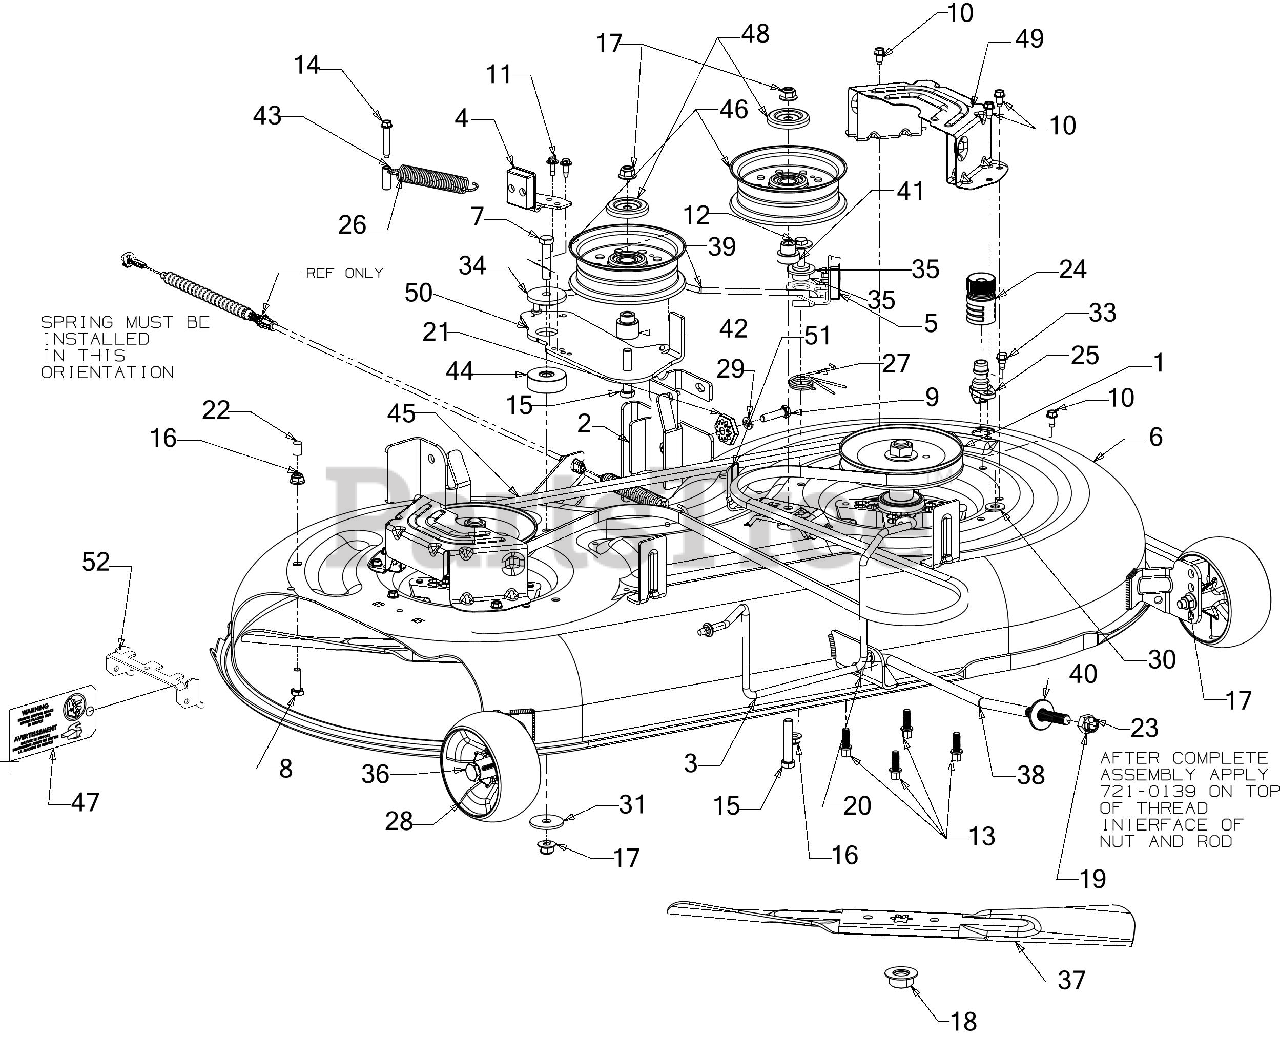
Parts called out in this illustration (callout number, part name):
1	SPINDLE ASSEMBLY
2	DECK HANGER BRACKET ASSEMBLY (LH)
3	BELT KEEPER ROD
4	DECK BRAKE ASSEMBLY
5	DECK BRAKE ASSEMBLY
6	42" DECK ASSEMBLY
7	HEX SCREW 3/8-16 x 1.75 GR5
8	SCREW 5/16-18 x 1.0 GR5
9	SCREW 5/16-18 x 1.25 GR5
10	SCREW 1/4-20 X.500
11	SCREW M6-1 x .625
12	SCREW 5/16-18 x 1.25 GR5
12	SCREW 5/16-18X1.25 GR 5
12	FLAT WASHER 344X1.00
13	SCREW 5/16-18 X .875
14	SCREW 1/4-20 x 1.50"
15	SCREW 3/8-16 x 2.0 GR 8
16	FLANGE LOCK NUT 5/16-18
18	HEX NUT
20	PIN:COTTER
21	DECK ADJUSTMENT
22	VINYL CAP
23	LOCTITE SEALANT (NOT SERVICEABLE)
24	WATER NOZZLE
25	DECK WASH NOZZLE
26	EXTENSION SPRING
27	TORSION SPRING
28	DECK WHEEL
29	LOCK WASHER 5/16
30	FLAT WASHER
31	FLAT WASHER .406X1.500X.105
32	SHOULDER SCREW
33	SHOULDER SCREW 1/4-20X.50 19"PSH
34	SHOULDER SPACER
35	SHOULDER SPACER .750 x .145
36	SHOULDER BOLT
37	21.23" BLADE (2N1)
38	DECK FRONT LIFT ROD
39	DECK BRAKE ROD
40	LIFT PIVOT CUP
41	SHOULDER SPACER
42	SHOULDER SPACER
43	SPACER
44	SPACER .385ID x 1.75OD x .585THK
45	V-BELT A x 96.5
46	IDLER PULLEY 4.50" DIA
48	IDLER PULLEY CAP
49	DECK BELT COVER 42
50	DECK IDLER BRACKET
51	BELT KEEPER
